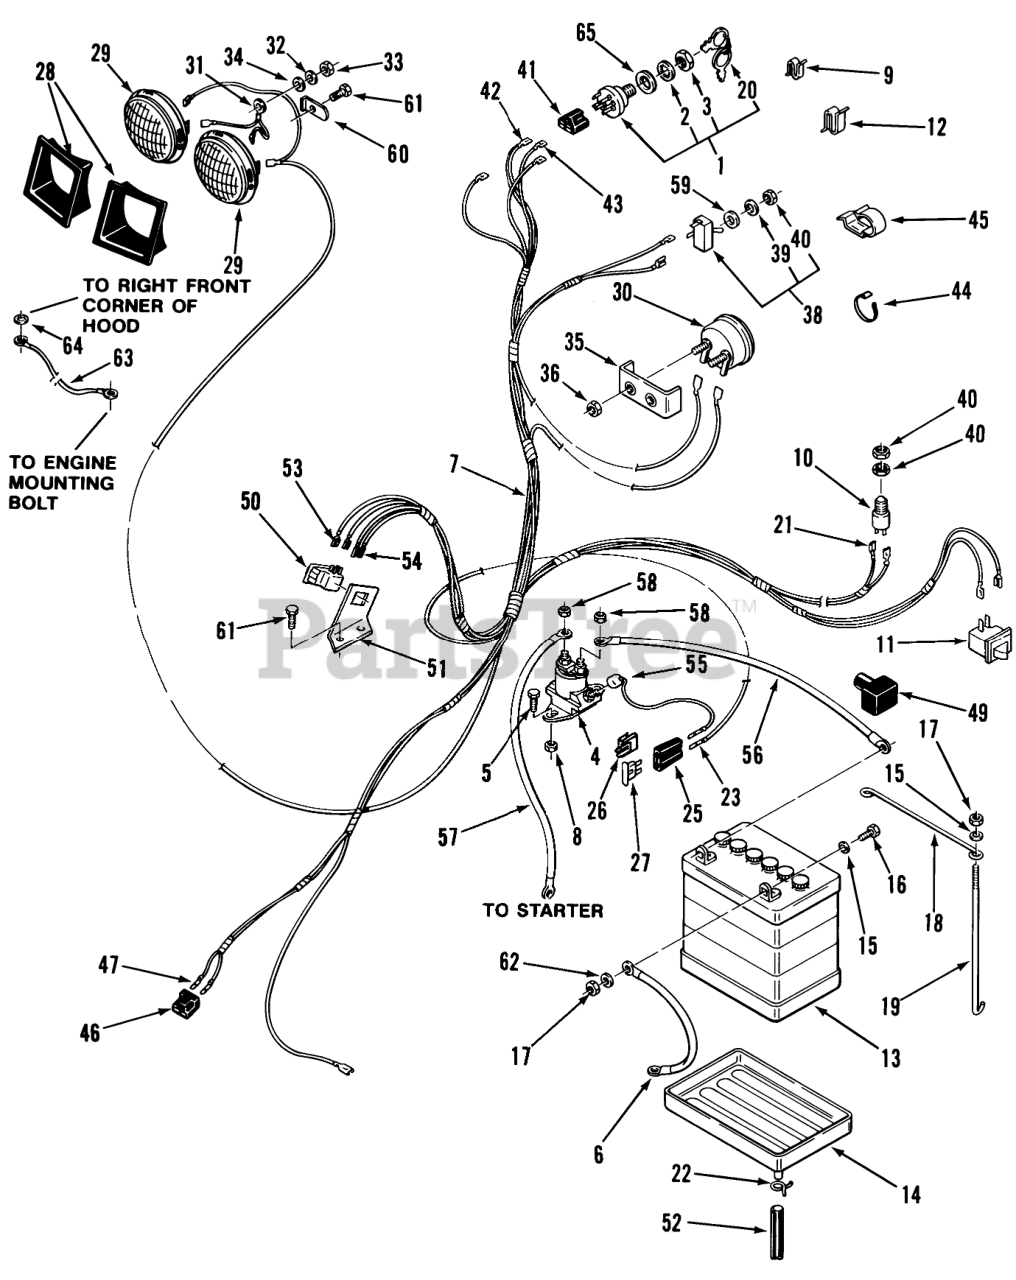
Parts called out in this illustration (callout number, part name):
1	ASSY-SWITCH IGNITION
2	LOCKWASHER
4	Solenoid
5	Screw
6	Wire
7	Wiring Harness Assy
8	Nut
9	SPEED CLIP
10	SWITCH-SEAT
11	SWITCH INTERLOCK
12	CLIP
13	Battery
14	TRAY-BATTERY
16	Bolt
17	Nut
18	ROD-HOLD DOWN
20	Key-EL
21	Connector
22	Clamp
23	TERMINAL-FUSE
25	AUTO-FUSEBLOCK TERM
27	FUSE-BLADE, 15 AMP
28	HEADLIGHT BEZEL ASSY.(SERVICE)
29	HEADLAMP
30	AMMETER W/CLAMP
31	LIGHT GROUND WIRE
32	Washer-Lock
33	Nut
34	WASHER 5/16 SAE
35	Clamp
36	HEX NUT 10-32 E.S.
38	SWITCH-LIGHTS
39	TAB-WASHER
40	NUT-HEX, SPECIAL
41	CONNECTOR-5 WAY-SERV
42	TERMINAL-TAB RCPT
43	Terminal
44	PLASTIC TIE
45	CLIP-WIRE
46	Conn Body Part of 7
47	Terminal
49	Boot
50	PTO Interlock Switch
51	BRACKET-SWITCH (NS)
52	TUBE-BATTERY DRAIN
53	Terminal
54	Wire Terminal (Part of 1)
55	Terminal Part of 5
56	Cable
57	Starter To Solenoid Cable 16.0 in. (40.6 cm) 216-5 Only
57	Wire
58	Nut
59	Washer
60	LOCK-HEADLIGHT
61	Bolt
62	Washer
63	WIRE GROUND
64	Washer-Lock
65	Washer
